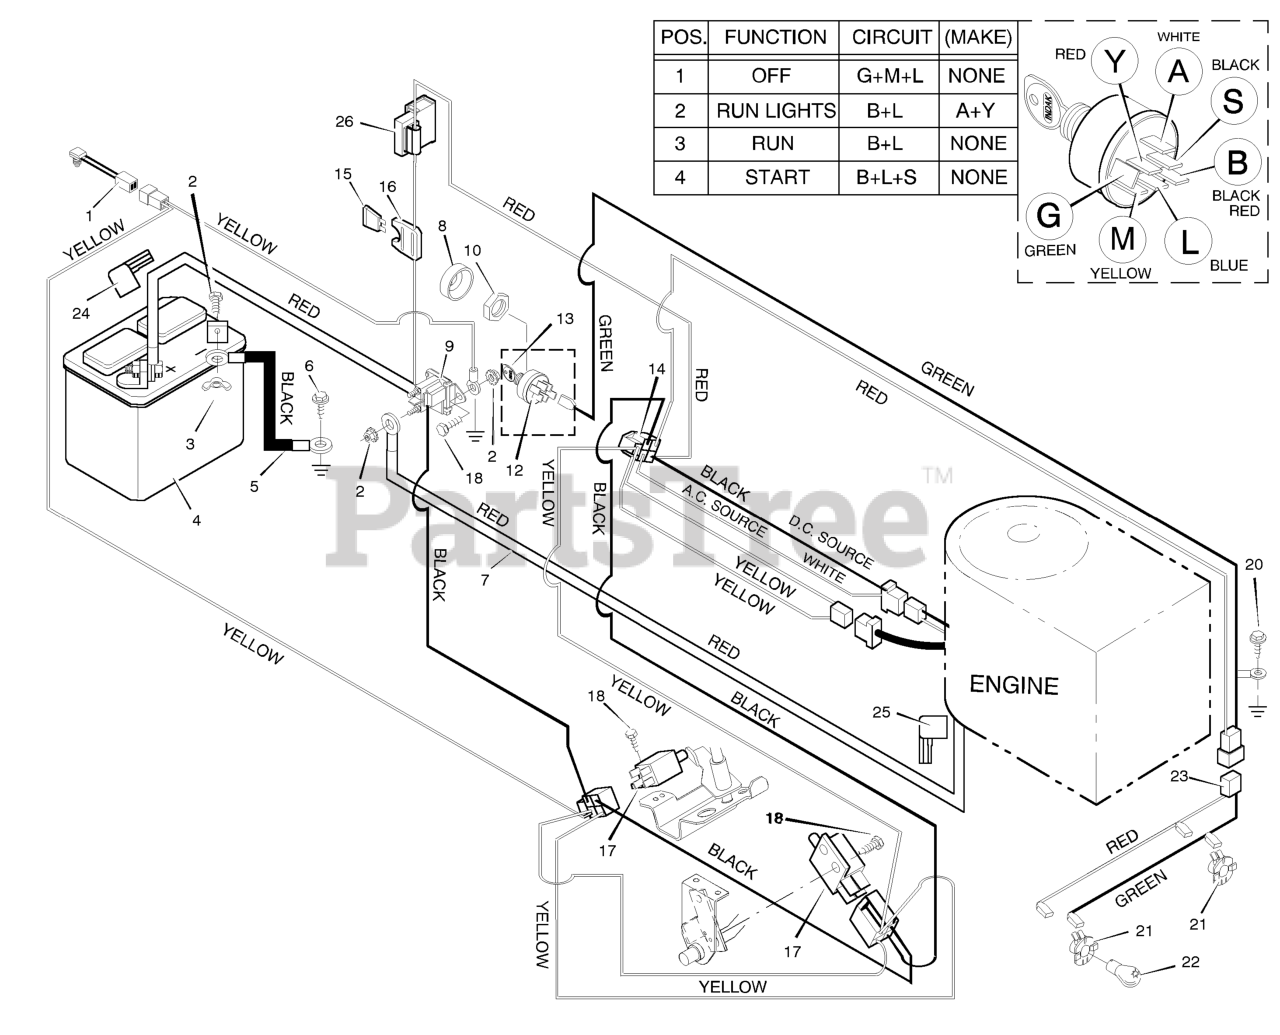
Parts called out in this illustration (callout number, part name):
1	Switch, Seat Sensor
2	Bolt
3	Wingnut
4	Battery
5	Cable, Battery Ground
7	Cable, Red Battery
8	Cap, Ignition
9	Solenoid
10	Nut
12	Switch, Ignition
13	Key, Ignition
14	Harness, Chassis Wire
16	Holder, Fuse
17	Switch, Clutch
20	Screw
21	Socket, Light
22	Bulb, Light
23	Harness, Light Wire
24	Cover, Terminal
25	Cover,
26	Ammeter
